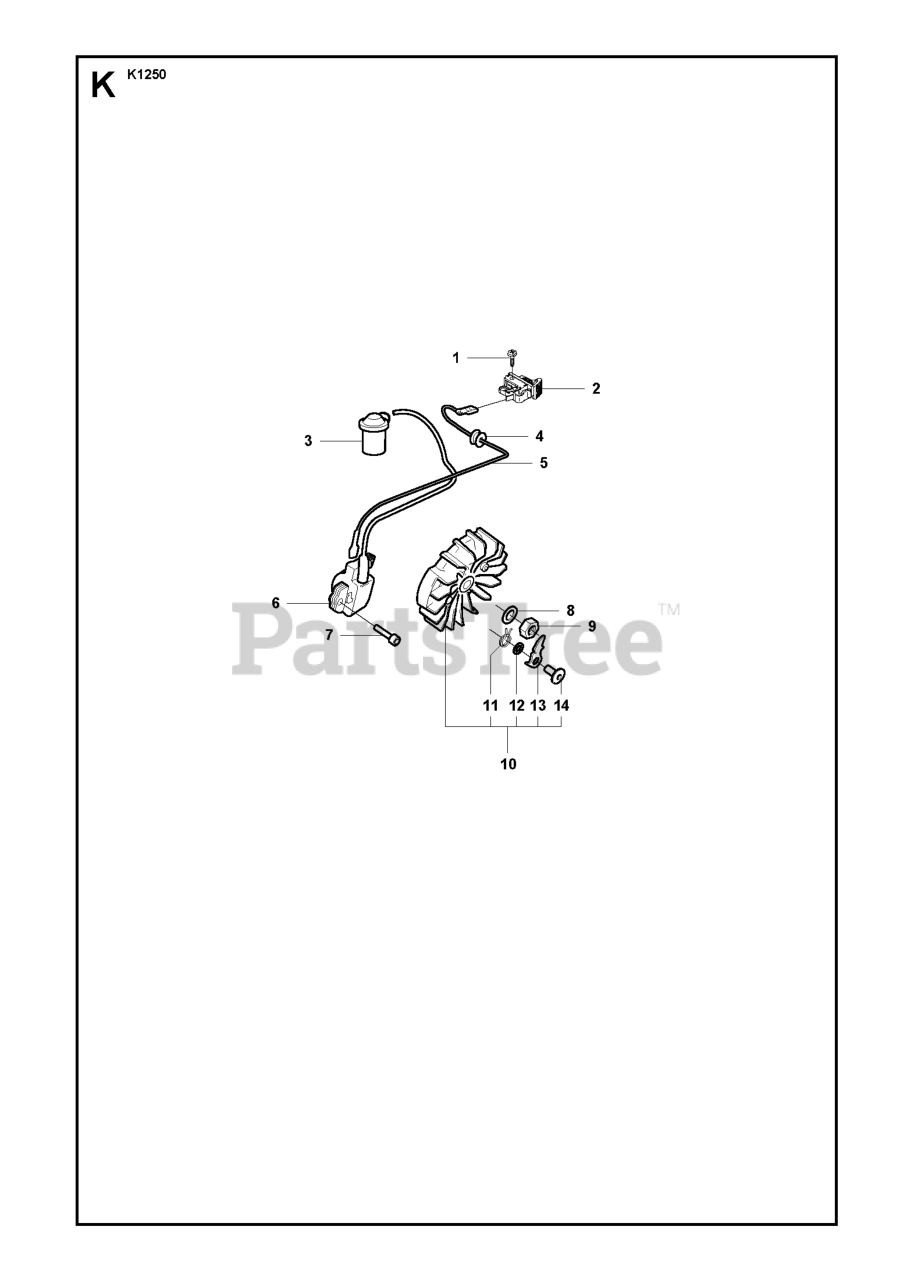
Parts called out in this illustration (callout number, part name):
1	SCREW
2	STOP SWITCH
3	SPARK PLUG CONN. KIT
6	IGNITION MODULE
8	SPRING WASHER 10.5X18
10	RP FLYWHEEL
14	SCREW M5X14
